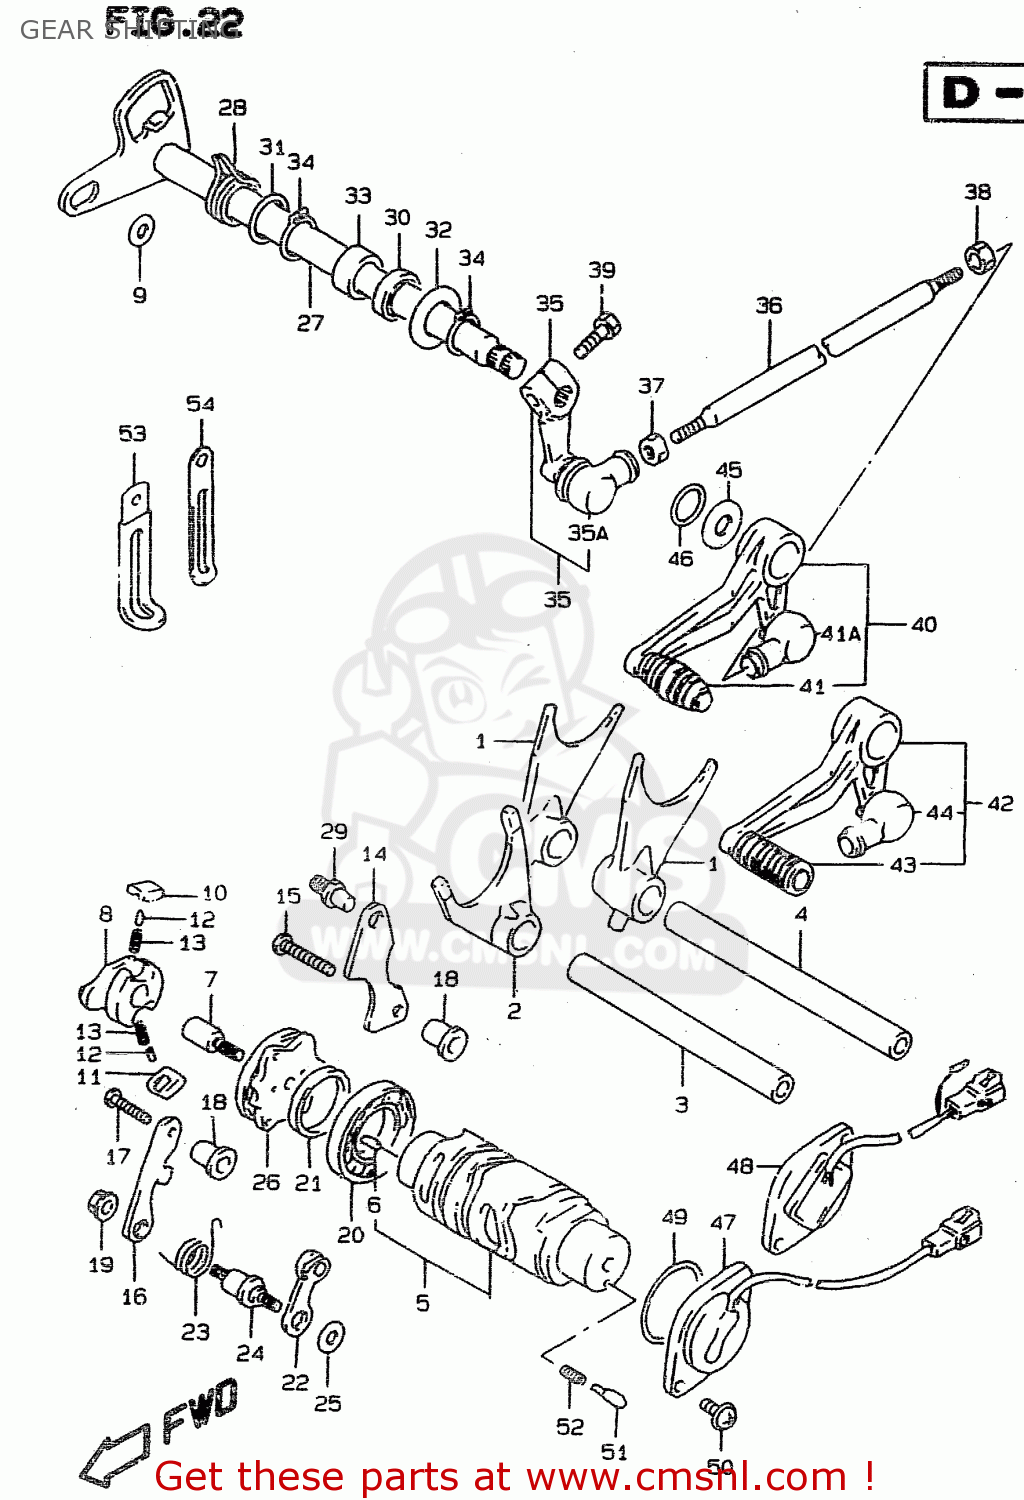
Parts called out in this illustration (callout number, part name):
1	FORK,GEAR SHIFT NO.1
2	FORK,GEAR SHIFT NO.3
3	SHAFT,GEAR SHIFT FORK
4	SHAFT,GEAR SHIFT FORK(L:128)
5	CAM,GEAR SHIFT
6	PIN
7	PIN,SHIFT CAM DRIVEN GEAR
8	SHIFTER,GEAR SHIFT CAM
9	SPACER(7X10X5)
10	PAWL,GEAR SHIFT NO.1
11	PAWL,GEAR SHIFT NO.2
12	PIN(5X8)
13	SPRING
14	LIFTER,GEAR SHIFT PAWL
15	SCREW 6X30
16	GUIDE,GEAR SHIFT CAM
17	SCREW
18	SPACER(6.1X10X16)
19	NUT
20	BEARING(25X47X8)
21	WASHER(25X32X3)
22	STOPPER,GEAR SHIFT CAM
23	SPRING,STOPPER ARM
24	SUPPORT,CAM STOPPER ARM
25	WASHER
26	PLATE,GEAR SHIFT CAM
27	SHAFT,GEAR SHIFT
28	SPRING
29	STOPPER,GEAR SHIFT CAM
30	SEAL,OIL(14X22X6)
31	WASHER,THRUST
32	WASHER(14X29X0.8)
33	BEARING(14X20X12)
34	CIRCLIP
35	ARM,GEAR SHIFT LINK
35A	COVER,DUST
36	ROD,GEAR SHIFT LINK
37	NUT
38	NUT
39	BOLT
40	LEVER ASSEMBLY,GEAR SHIFTING
41	RUBBER,GEAR SHIFT PEDAL
41A	COVER,DUST
42	LEVER ASSY,GEAR SHIFT
43	RUBBER,GEAR SHIFT PEDAL
44	COVER,DUST
45	WASHER(14X27X4)
46	WASHER(18X24X1)
47	BODY, GEAR SHIFTING SWITCH
48	BASE ASSY,GEAR SHIFT TERMINAL
49	O RING(D:2.4,ID:35.5)
50	SCREW
51	PIN(5X15.5)
52	SPRING
53	CLAMP
54	CLAMP
